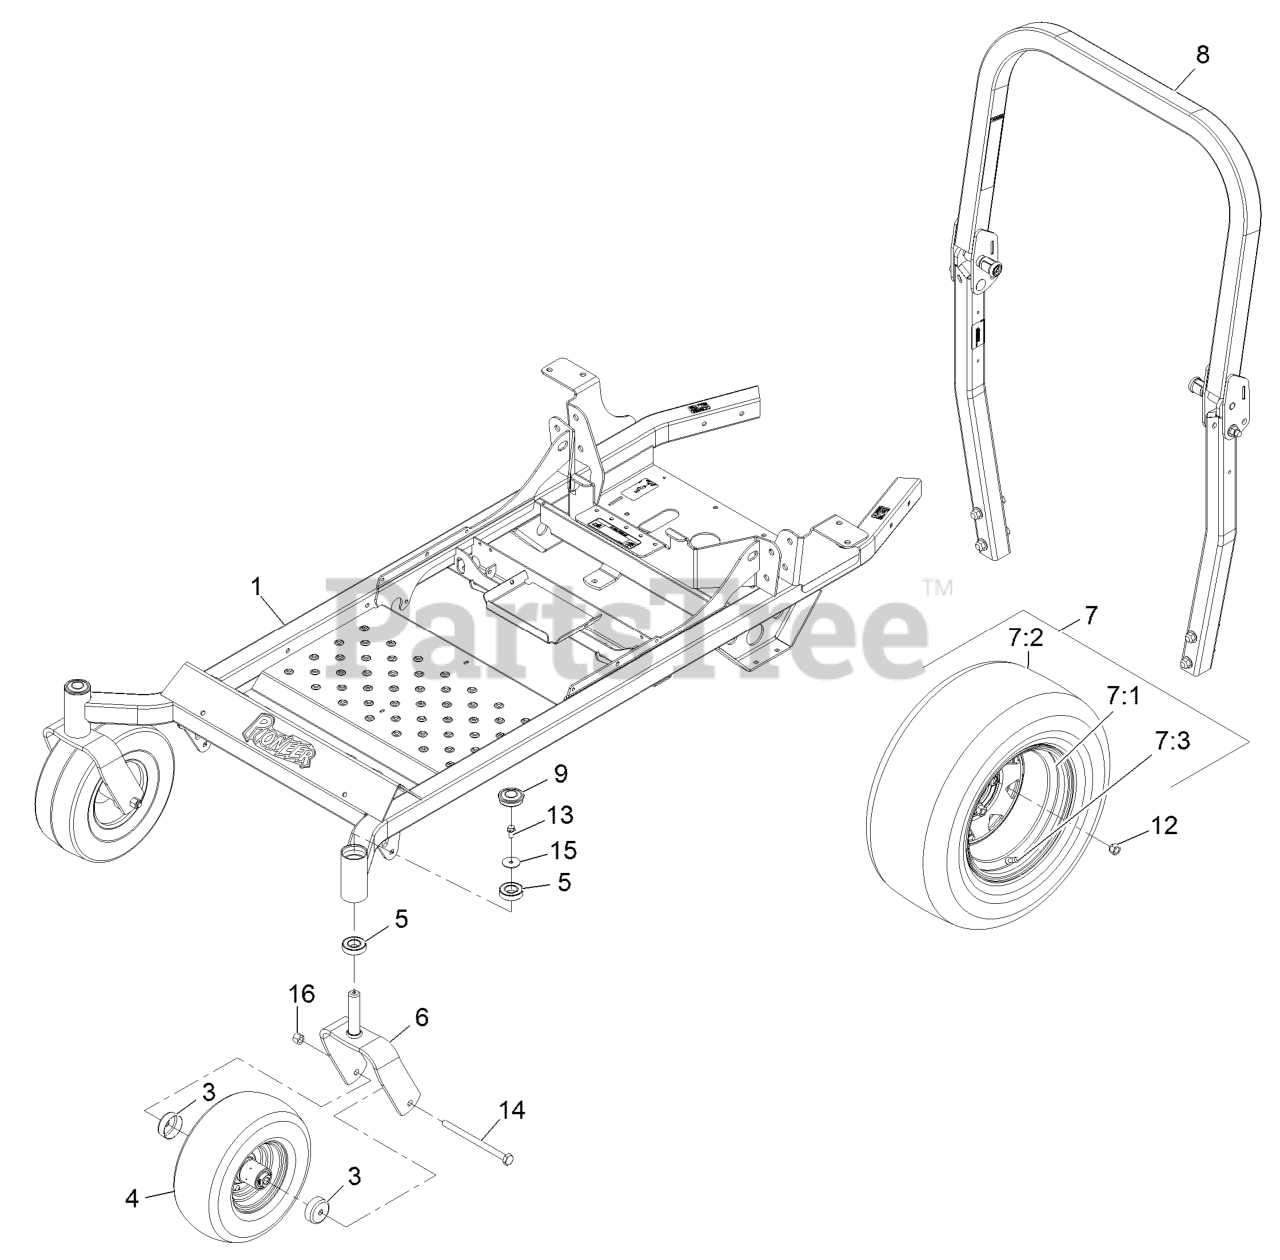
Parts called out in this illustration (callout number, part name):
1	FRAME ASM-60
3	GUARD-SEAL
4	ASM, WHEEL AND TIRE W/ AX
5	BEARING-BALL
6	CASTER FORK
7	WHEEL AND TIRE ASM
7:2	TIRE
7:3	Stem-Valve
8	ASM-ROPS PIONEER
9	CAP-GREASE
12	NUT-LUG
13	SCREW-HHF
14	SCREW-HH
15	WASHER-FLAT
16	NUT-LOCK, NI
